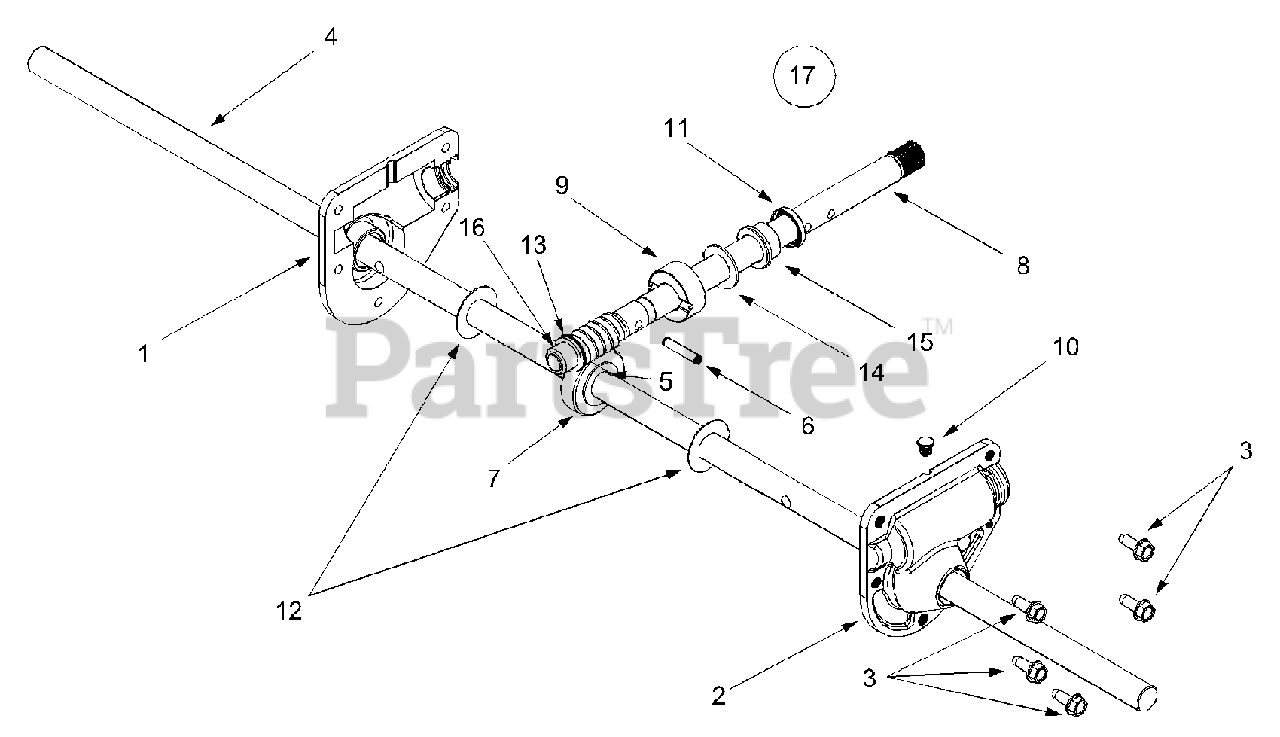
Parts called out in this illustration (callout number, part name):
1	RH Housing
2	LH Housing w/Fitting Hole
3	Self Tapping Screw, 1/4-20 x .75
4	Spiral Axle, 30"
5	Hi-Pro Key, 3/16 x 5/8
6	Spring Spirol Pin, .25 x 1.25
7	Worm Gear, 20-tooth
8	Worm Shaft
9	Thrust Collar
10	Grease Plug
11	Grease Seal
12	Flat Washer, .76 x 1.5 x .030
13	Flat Washer, .508 x 1.0 x .020
14	Flat Washer, .76 x 1.5 x .060
15	Flange Bearing, .75 x 1.0 x .59
16	Flange Bearing, .503 ID x .75 OD
17	Gear Assembly Complete, 30"
